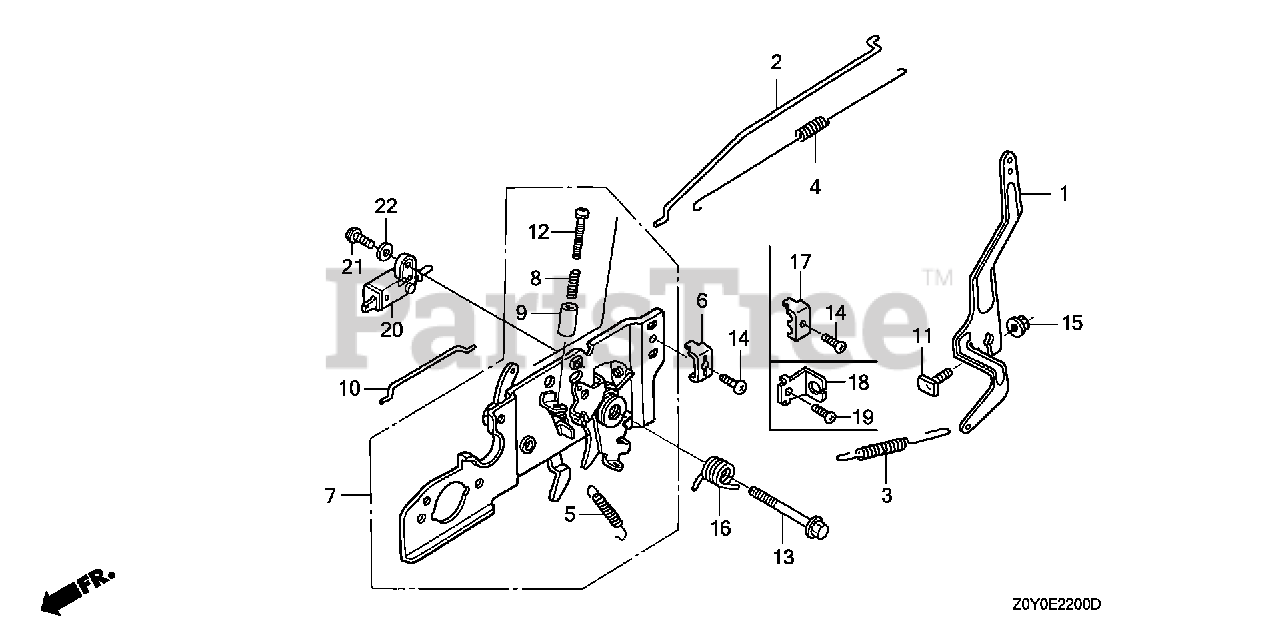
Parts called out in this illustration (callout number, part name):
1	ARM, GOVERNOR
2	ROD, GOVERNOR
3	SPRING, GOVERNOR
4	SPRING, THROTTLE RETURN
5	SPRING, LEVER
6	HOLDER, CABLE
7	BASE, CONTROL
10	ROD, CHOKE
11	BOLT, GOVERNOR ARM
13	BOLT, FLANGE (6X45) (CT200)
14	SCREW, PAN (5X16)
15	NUT, FLANGE (6MM)
16	SPRING, CONTROL LEVER RETURN
18	HOLDER, CABLE
19	SCREW, PAN (5X8)
20	SWITCH ASSY., ENGINE STOP (N.O)
21	SCREW-WASHER (4X12)
22	WASHER, PLAIN (4MM)
